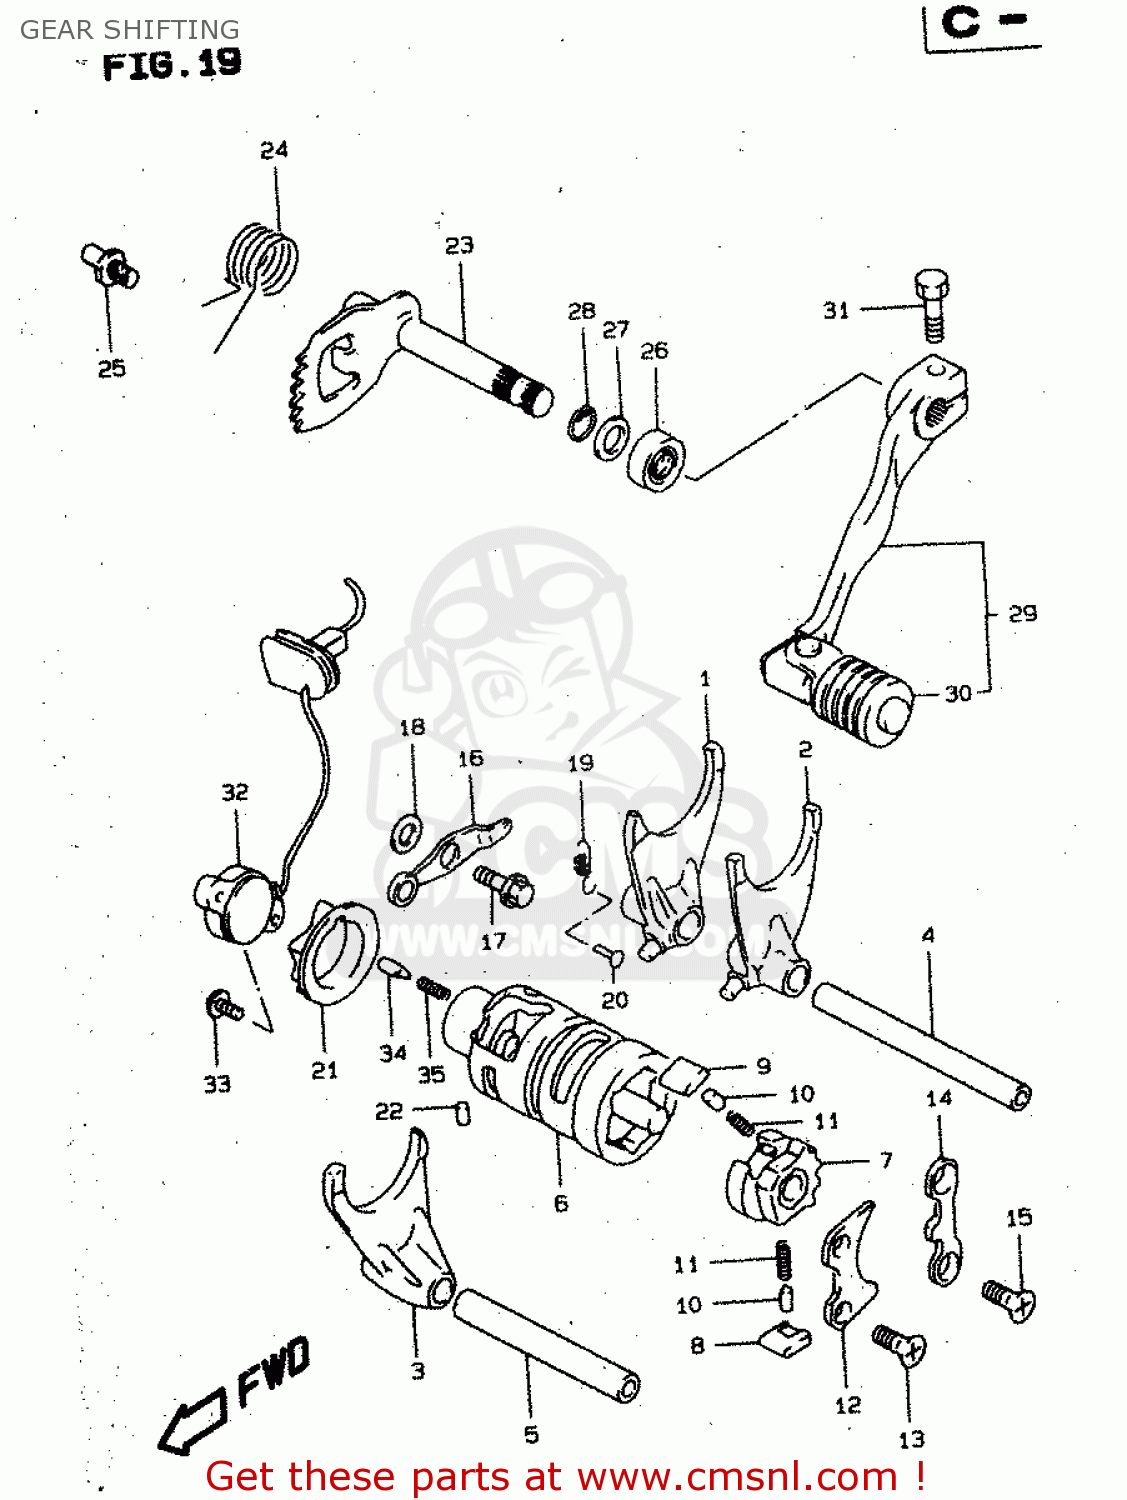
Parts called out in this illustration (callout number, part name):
1	FORK,GEAR SHIFT NO.1
2	FORK,GEAR SHIFT NO.2
3	FORK,GEAR SHIFT NO.3
4	SHAFT,GEAR SHIFT FORK
5	SHAFT,GEAR SHIFT FORK
6	CAM,GEAR SHIFT
7	GEAR,GEAR SHIFT CAM DRIVEN
8	PAWL,GEAR SHIFT NO.1
9	PAWL,GEAR SHIFT NO.2
10	PIN(5X8)
11	SPRING
12	LIFTER,GEAR SHAFT PAWL
13	SCREW
14	STOPPER,GEAR SHIFT POLE
15	SCREW
16	STOPPER,GEAR SHIFT CAM
17	BOLT(6X14.6)
18	WASHER
19	SPRING
20	RIVET
21	PLATE,GEAR SHIFT CAM STOPPER
22	PIN
23	SHAFT,GEAR SHIFT
24	SPRING
25	STOPPER,GEAR SHIFT CAM
26	OIL SEAL
27	WASHER
28	CIRCLIP,12 MM
29	LEVER ASSY,GEAR SHIFT
30	RUBBER,GEAR SHIFT PEDAL
31	BOLT
32	BASE ASSY,GEAR SHIFT TERMINAL
33	SCREW
34	PIN(5X15.5)
35	SPRING
